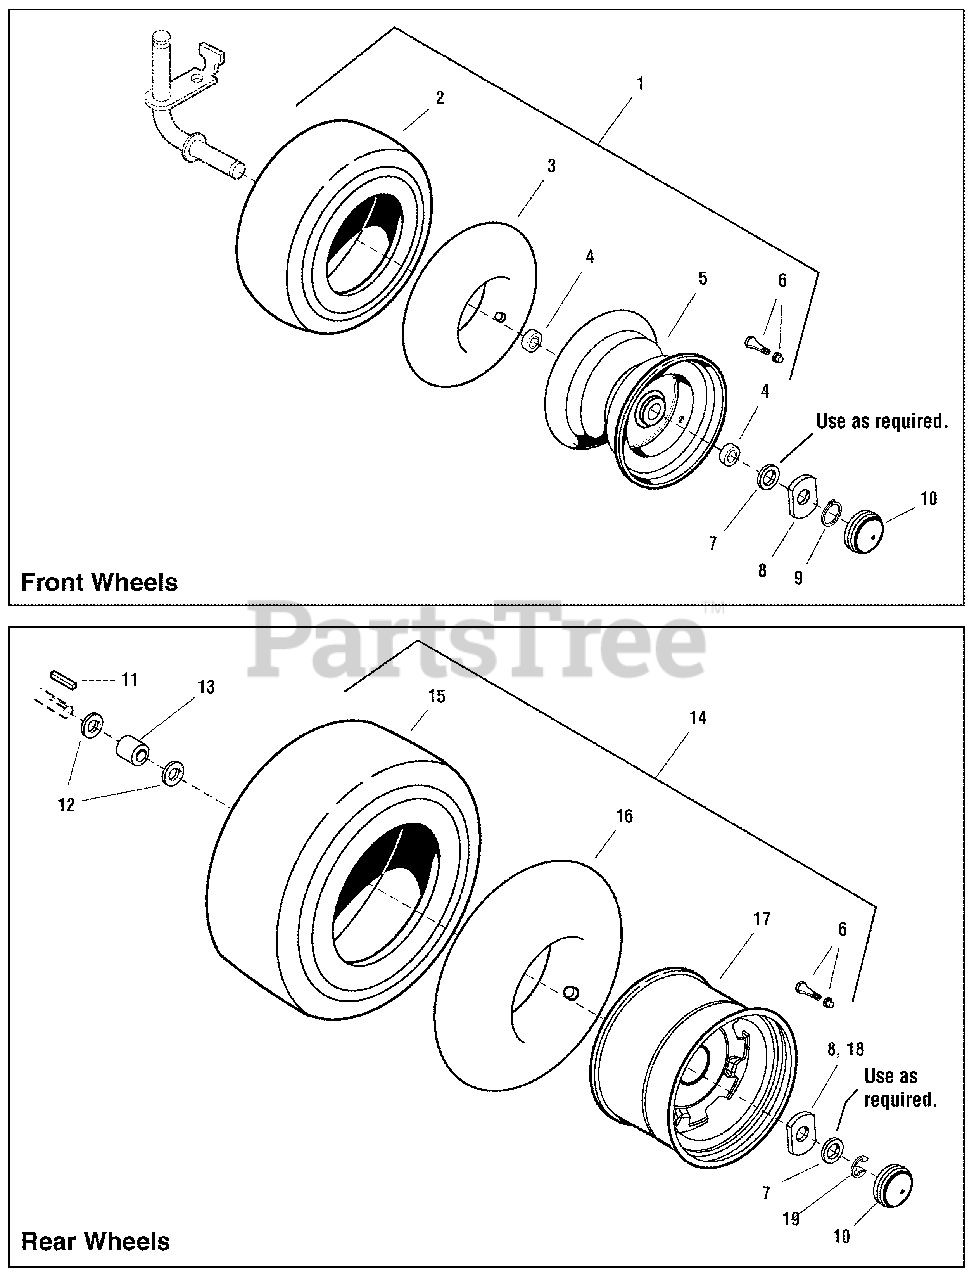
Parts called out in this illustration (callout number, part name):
1	WHEEL & TIRE ASSEMBLY, Front, (Includes Ref. Nos. 2, 3, 4, 5, & 6)
2	TIRE, 15 x 6, Super Turf
3	TUBE, Tire, Front, 4.10/3.50
4	BEARING, Ball
5	WHEEL, 4-1/2" x 6"
6	VALVE STEM & CAP ASSEMBLY
7	WASHER, 1, (As Required for All Front, As Required for K62 Rear)
8	WASHER, Special, (As Required for All Front, As Required for K62 Rear)
9	RING, Retainer
10	CAP, Hub, Gray
11	KEY, Hi Pro 1/4 x 2 (Units with K62)
11	KEY, Parellel, 3/16 x 3/16 x 1-1/2 (Units with K57)
12	WASHER, 1, (Units with K62)
12	WASHER, 3/4 (Units with K57)
13	SPACER, (Units with K62)
13	SPACER, (Units with K57)
14	WHEEL & TIRE ASSEMBLY, (Units with K57 - Includes Ref. Nos. 6, 15, 16 & 17)
14	WHEEL & TIRE ASSEMBLY, (Units with K62 - Includes Ref. Nos. 6, 15, 16 & 17)
15	TIRE, 20 x 10, 8 Super Turf
16	TUBE, Tire, 20 x 8, Rear
17	WHEEL, 7 x 7.96, W/ 1 OD Shaft (Units with K62)
17	WHEEL, 7 x 7.96, W/ 3/4 OD Shaft (Units with K57)
18	WASHER, Special, (Units with K57)
19	RING, "E" External, (Units with K57)
19	RING, "E" External, (Units with K62)
